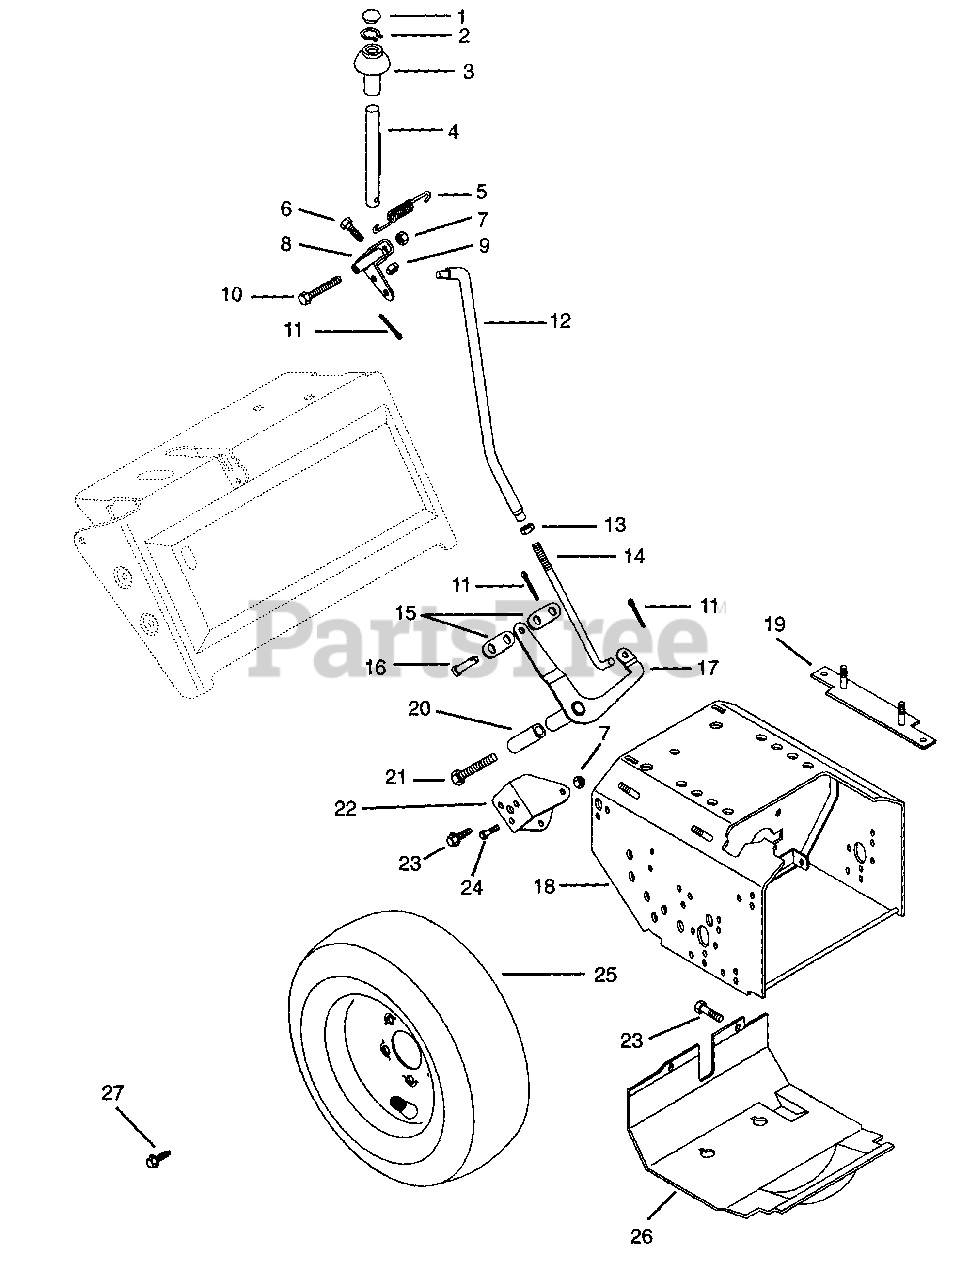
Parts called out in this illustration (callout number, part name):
1	HOLE PLUG
2	RG-RTNG-EXT .500X.015
4	ROD
5	SG-TENS .055X.33X1.31 WLD 7
6	@BLT-HEX .25-20X1.00 GR5 YWZC
7	@NUT-LK-CTR .31-18 YWZC
9	@NUT-LK-CTR .25-20 YWZC
10	@BLT-HEX .31-18X3.50 GR5 YWZC
11	@PIN-CTR .09X.75 EXTPRSQCT YWZ
12	UPPER SHIFT ROD
13	NUT-HEX .312-24 YWZC
14	LOWER SHIFT ROD
15	SHIFT LINK
16	CLEVIS PIN
17	LEVER - SHIFT ARM
19	BOLT STRAP
20	SPACER .5 X .33 X 2.4
21	@BLT-HEX .31-18X3.00 GR5 YWZC
22	BRACKET SHIFT LEVER
23	@SCR-TAP .31-18X.50 HWH TR YWZ
24	@BLT-HEX .31-18X.50 GR5 YWZC
25	TUBE
25	WHL
25	TIRE 4.80-8 NHS
25	TIRE 16X6.50-8 SNO-HOG TREAD
25	T/WHL ASSY 4.80-8
25	T/WHL ASSY 16X6.50-8 SNO-HOG
26	BOTTOM COVER
27	SCR-TAP .500-20X.62 HH YWZC
